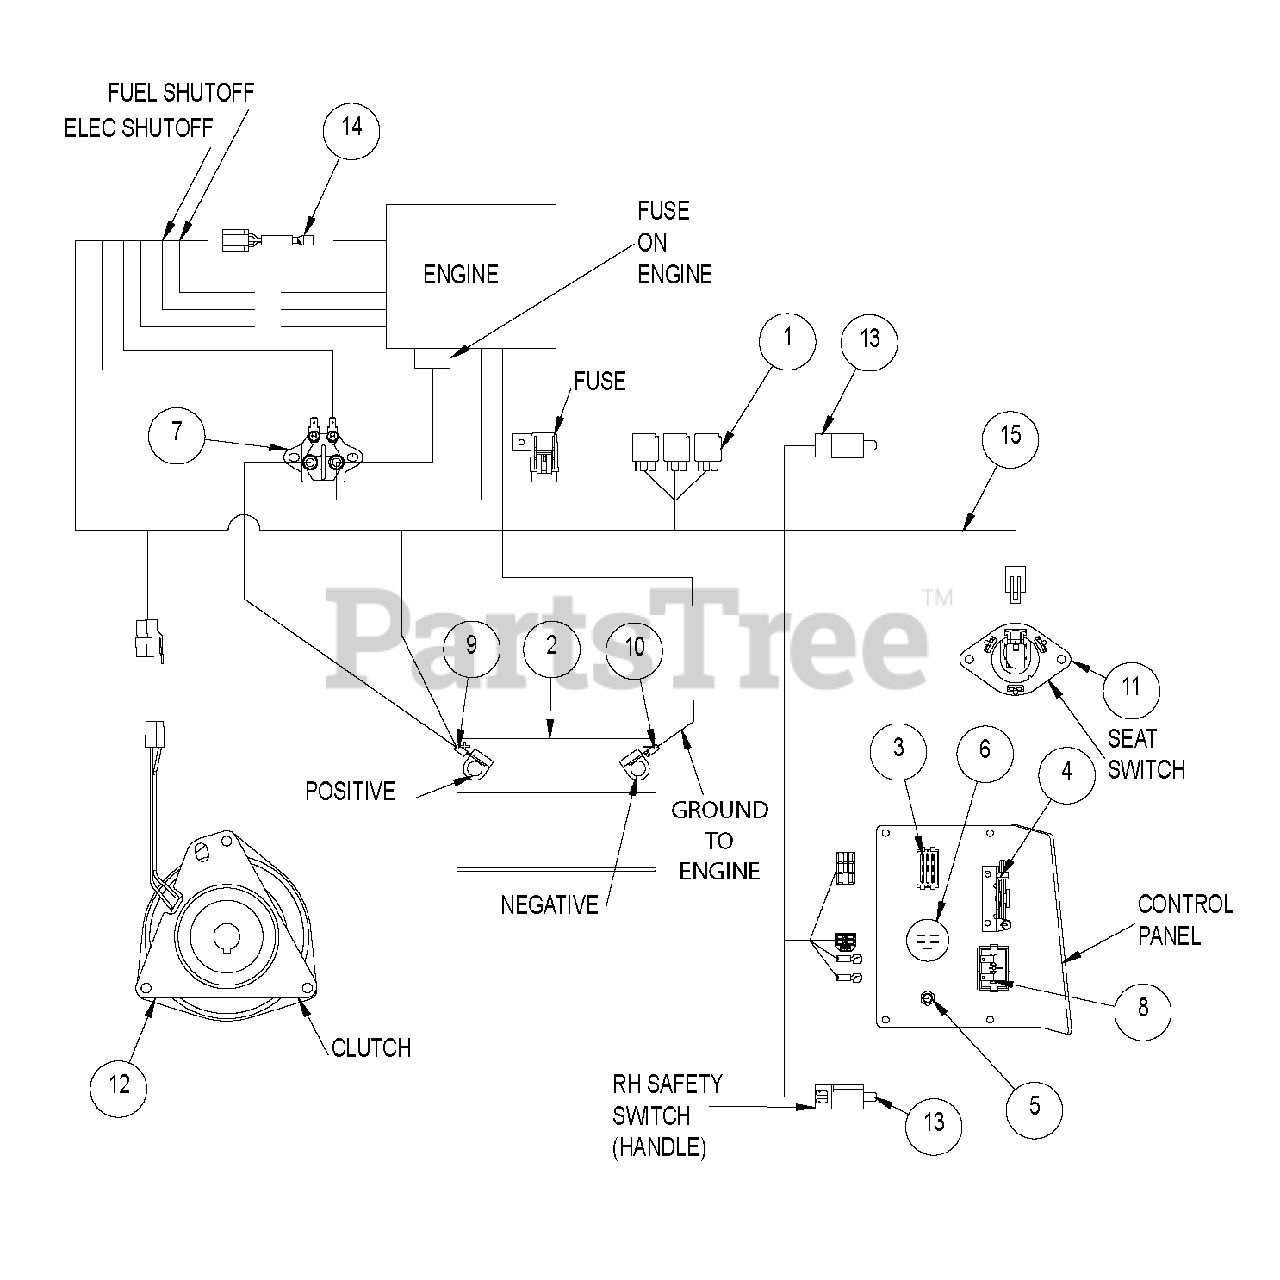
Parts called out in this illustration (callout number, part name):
1	RELAY, ISO MINI ELEC.
2	BATTERY, 12V - SEALED
3	SWITCH, PTO ENGAGEMENT
4	CABLE, THROTTLE
5	CABLE, CHOKE 48.0"
6	SWITCH, KEY - 3 POSITION
7	SOLENOID, 12V STARTER
8	METER, HOUR - LCD ALT. (ENM)
9	CABLE, 12" STARTER
10	CABLE, BATTERY - 35" GROUND
11	SEAT SWITCH S/O
12	CLUTCH, ELECT - OGURA GT, 2.5
12	CLUTCH, ELECT - OGURA, GT2.5
13	SWITCH, PLUNGER DP - N.O.-N.C.
14	ADAPTER HARNESS, 19KAI/23KAW
14	HARNESS, KOHLER ADAPTER
15	HARNESS, POWER UNIT WIRE
